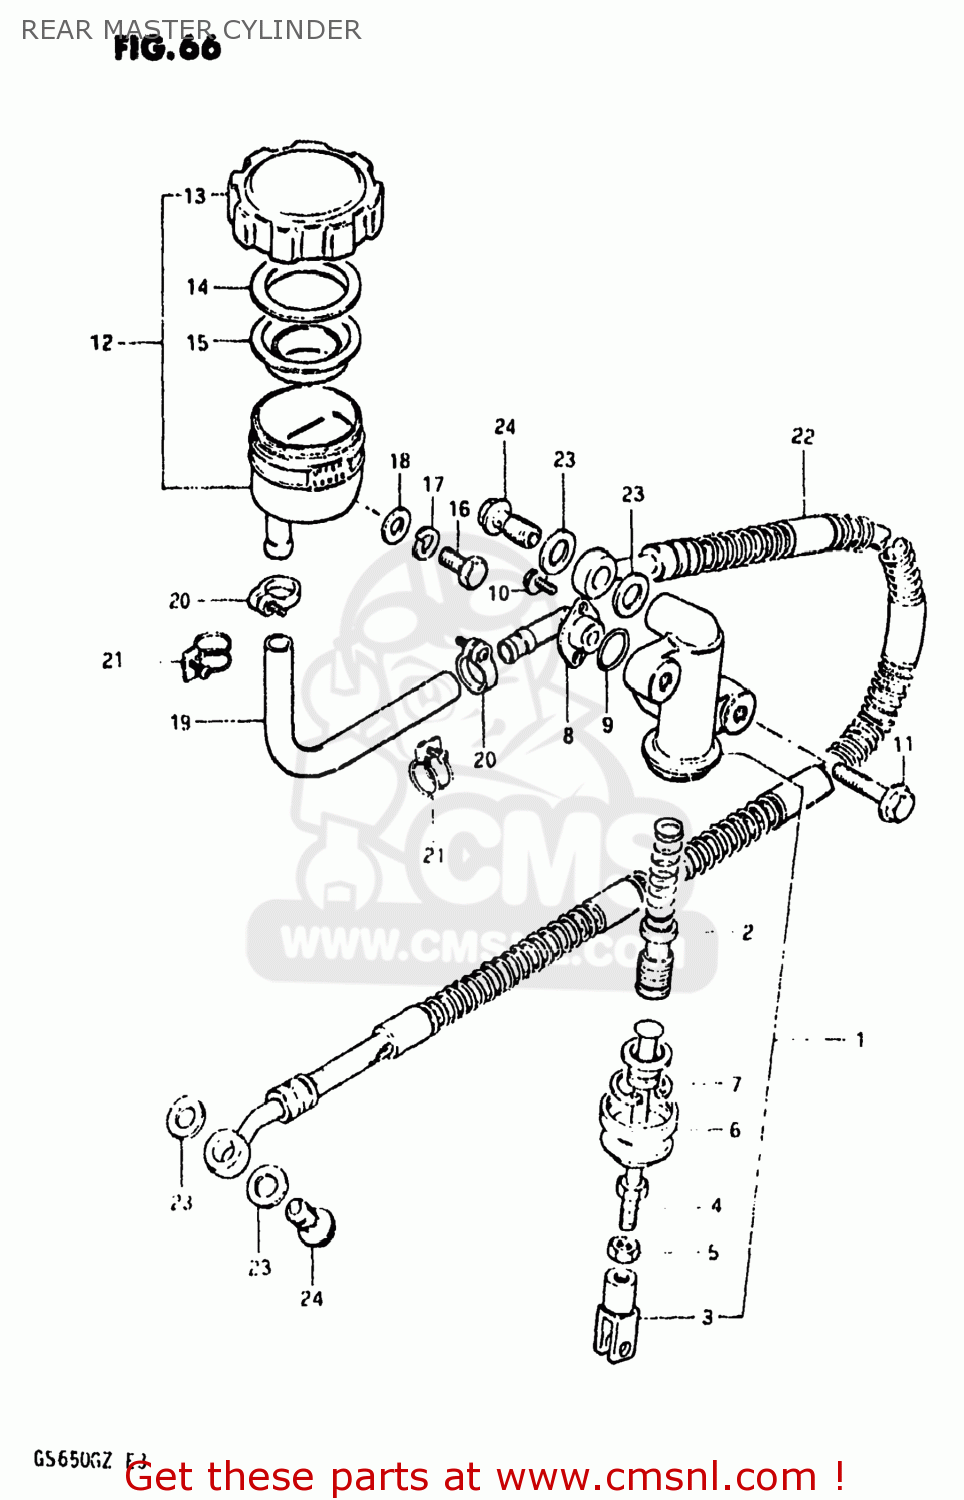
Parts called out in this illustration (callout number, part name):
1	CYLINDER ASSEMBLY,REAR MASTER
2	PISTON/CUP SET
3	YOKE
4	ROD,PUSH
5	NUT
6	BOOT
7	CIRCLIP
8	CONNECTOR,HOSE
9	O RING
10	SCREW
11	BOLT
12	TANK ASSEMBLY,RESERVOIR
13	CAP
14	PLATE,DIAPHRAGM
15	DIAPHRAGM
16	BOLT, UPPER
17	LOCK WASHER
18	WASHER
19	HOSE,RESERVOIR TANK
20	CLAMP
21	CLAMP
22	HOSE,REAR BRAKE
23	WASHER
24	BOLT,UNION
